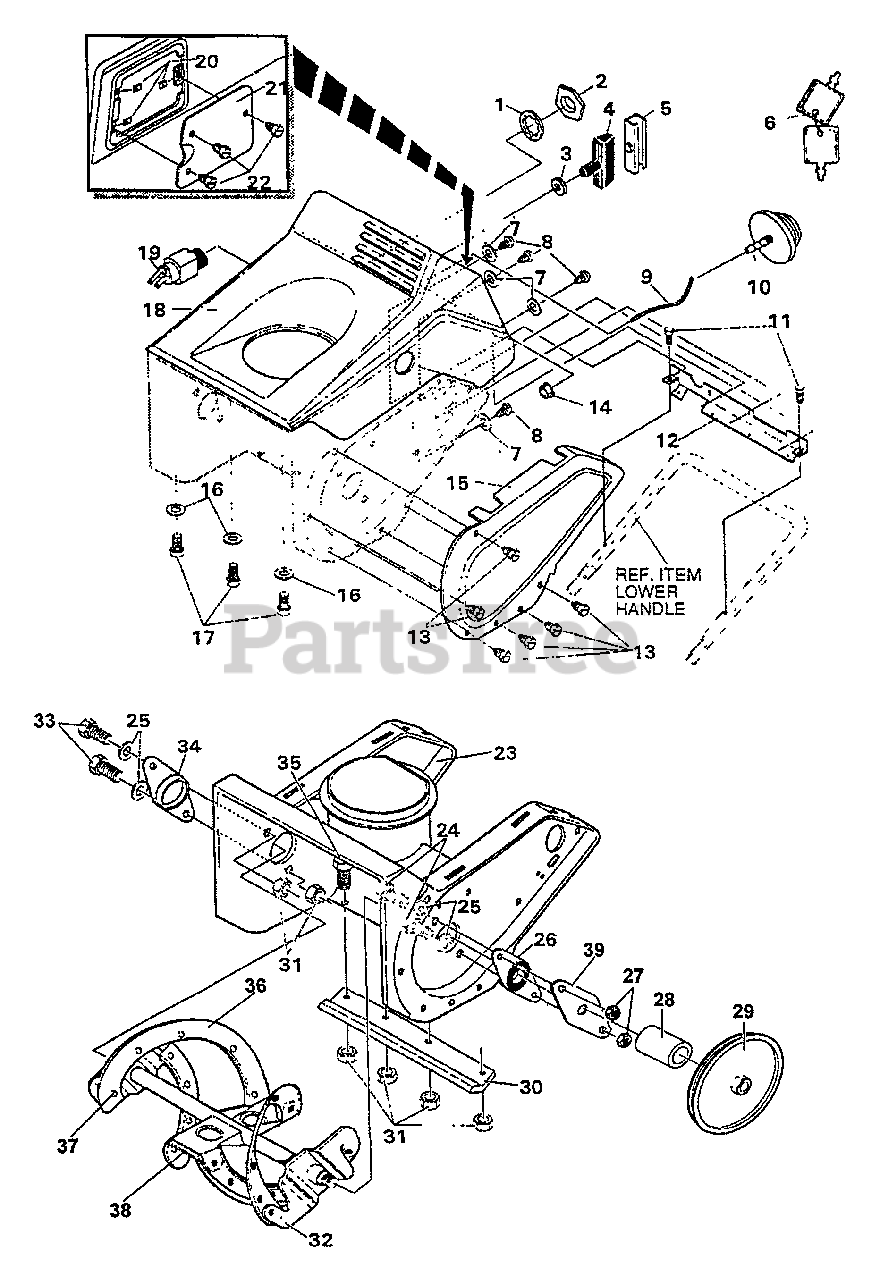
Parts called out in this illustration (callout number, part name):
1	WASHER
2	NUT
3	GROMMET & WASHER, ROPE GUIDE
4	KNOB, TEE
4	KNOB, SHORT SHANK
5	INSERT METAL, KNOB
6	KEYS & RING ASSY
7	WASHER
8	SCREW - 10-24 X .63"
9	HOSE, PRIM 5.75 LONG
10	PRIMER, ENGINE 2CY
11	SCREW - 10-24 X .63"
12	BRACKET, SHROUD MNTG
13	SCREW - 10-24 X 3/8"
14	NUT - 1/4-20 -- KEPS
15	COVER, BELT
16	WASHER
17	SCREW - 10-14 X .63"
18	COVER - TOP
19	SWITCH, IGNITION
20	NUT
21	DOOR, ACCESS
22	SCREW - 10-16 X .75"
23	HSNG, ASSY AUG 21"
24	SCREW - 1/4-20
25	WASHER
26	BEARING ASSY
27	NUT - 1/4-20
28	SPACER, SLEEVE .640X.88X.732
29	PULLEY, V3L 6.00X.75 20 GA
30	BLADE, SCRAPER
31	LOCKNUT - 1/4-20
32	AUGER ASSY - 21"
32A	AUGER ASSY
33	SCREW - 1/4-20 X 7/8"
34	BEARING, FLANGE
35	SCREW - 1/4-20 X 5/8"
36	AUGER, BLADE STRIP
37	RIVET - .250 X .5"
38	AUGER, CENTER BLADE STRIP
39	RETAINER, BEARING
